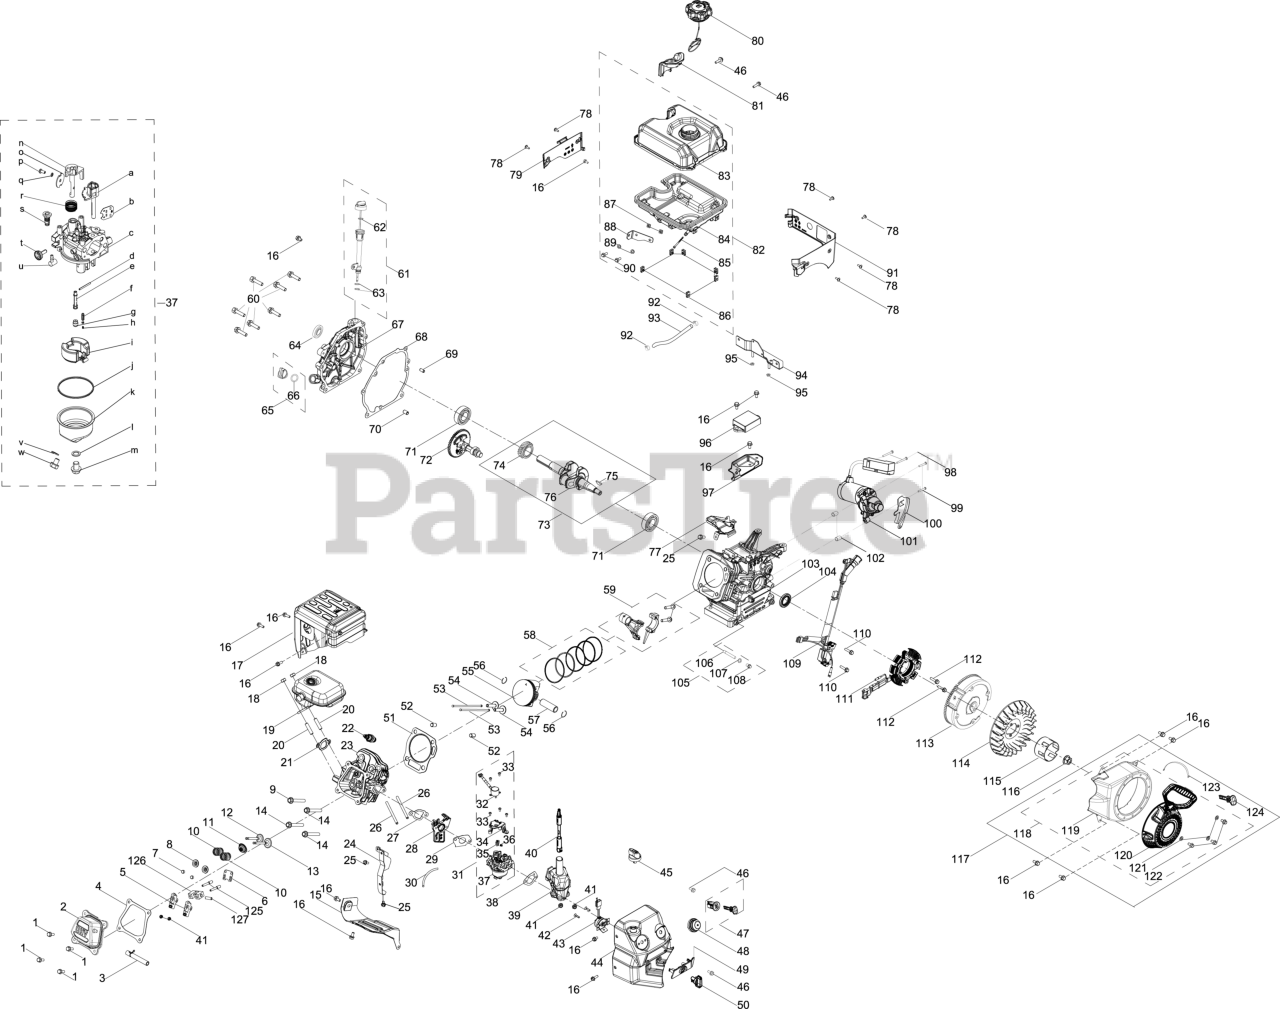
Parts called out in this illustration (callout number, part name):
1	BOLT M6 x 16
2	VALVE COVER
3	BREATHER HOSE
4	VALVE COVER GASKET
5	ROCKER ARM ASSEMBLY
6	PUSH ROD GUIDE
7	EXHAUST VALVE ADJUSTER
8	EXHAUST VALVE SPRING RETAINER
9	BOLT M10-1.25 x 70
10	VALVE SPRING
11	INTAKE VALVE SEAL
12	EXHAUST VALVE
13	INTAKE VALVE
14	SCREW M10-1.25 x 65 x GR10.9
15	AIR SHIELD
16	BOLT M6-1 x 12 GR8.8
17	MUFFLER GUARD
19	MUFFLER
21	MUFFLER GASKET
22	SPARK PLUG (F6RTC/RN11YC/BPR6ES)
23	CYLINDER HEAD
24	SNOW GUARD
25	BOLT M6-1 x 12 GR8.8
26	STUD M6 x 90
27	CARBURETOR INSULATOR GASKET
28	INSULATOR
29	CARBURETOR GASKET
30	PRIMER HOSE
31	CARBURETOR Assembly
32	THROTTLE MOTOR
33	SCREW M4x8
34	MOTOR BASE
35	CARBURETOR DAMPER
36	DAMPER SPRING
37	CARBURETOR
38	CARBURETOR GASKET PLATE
39	AIR/HEATER INTAKE BOX
40	CHOKE LEVER
41	HEX NUT
43	SPEED CONTROL SWITCH
44	CONTROL PANEL
45	CHOKE KNOB
46	BOLT M6-1 x 18 GR8.8
47	ENGINE KEY SWITCH ASSEMBLY
49	SPEED KNOB COVER
50	SPEED CONTROL KNOB
51	CYLINDER HEAD GASKET
52	Trigger Ignition Coil
53	PUSH ROD (SINGLE)
54	TAPPET
55	PISTON
56	PISTON PIN SNAP RING
57	PISTON PIN
58	PISTON RING SET 75MM
59	CONNECTING ROD
60	BOLT M8x32
61	DIPSTICK ASSEMBLY
63	OIL FILL TUBE O-RING
64	OIL SEAL
65	OIL PLUG
66	O-RING 15.8 x 2.5
67	CRANKCASE COVER
68	CRANKCASE GASKET
69	DOWEL PIN 7 X 14
70	DOWEL PIN 9 X 14
71	BALL BEARING
72	CAMSHAFT
73	CRANKSHAFT
74	TIMING GEAR
75	WOODRUFF KEY
76	Crankshaft
77	SHROUD
78	Bolt, M5X14
79	FUEL TANK SHROUD (REAR)
80	FUEL CAP
82	FUEL TANK
83	Not Serviceable/ Order Complete Assembly
84	Not Serviceable/ Order Complete Assembly
85	FUEL FILTER
86	FUEL TANK MOUNT
87	NUT M6
88	FUEL TANK MOUNT TAB
89	WASHER 6.5 x 1.5 x 12
90	BOLT M6 x 20
91	FUEL TANK SHROUD (LH)
92	CARBURETOR HOSE CLAMP
93	FUEL HOSE
94	FUEL TANK BRACKET
95	HEX NUT
96	EGOV ECM
97	SWITCH BOX BASE
99	BOLT M6-1 x 32 GR8.8
100	LOWER HOUSING
101	ELECTRIC STARTER
102	DOWEL PIN
103	CRANKCASE
104	OIL SEAL
105	OIL DRAIN PIPE
106	OIL DRAIN PIPE
107	FLAT WASHER
108	OIL DRAIN PLUG
109	IGNITION MODULE
110	BOLT M6-1 x 25 GR8.8
111	CHARGING COIL
112	BOLT-M6-1 x 28 GR8.8
113	FLYWHEEL
114	COOLING FAN
115	STARTER CUP
116	FLYWHEEL NUT M14-1.5
117	Not Serviceable/ Components Only
118	RECOIL STARTER
119	BLOWER HOUSING
120	RECOIL STARTER
121	FLAT WASHER
122	BOLT M6 x 10
123	CABLE TIE 3x150
124	IGNITION KEY
125	PIVOT BOLT
126	ROCKER ARM PIVOT BLOCK
127	ROCKER ARM SHAFT
